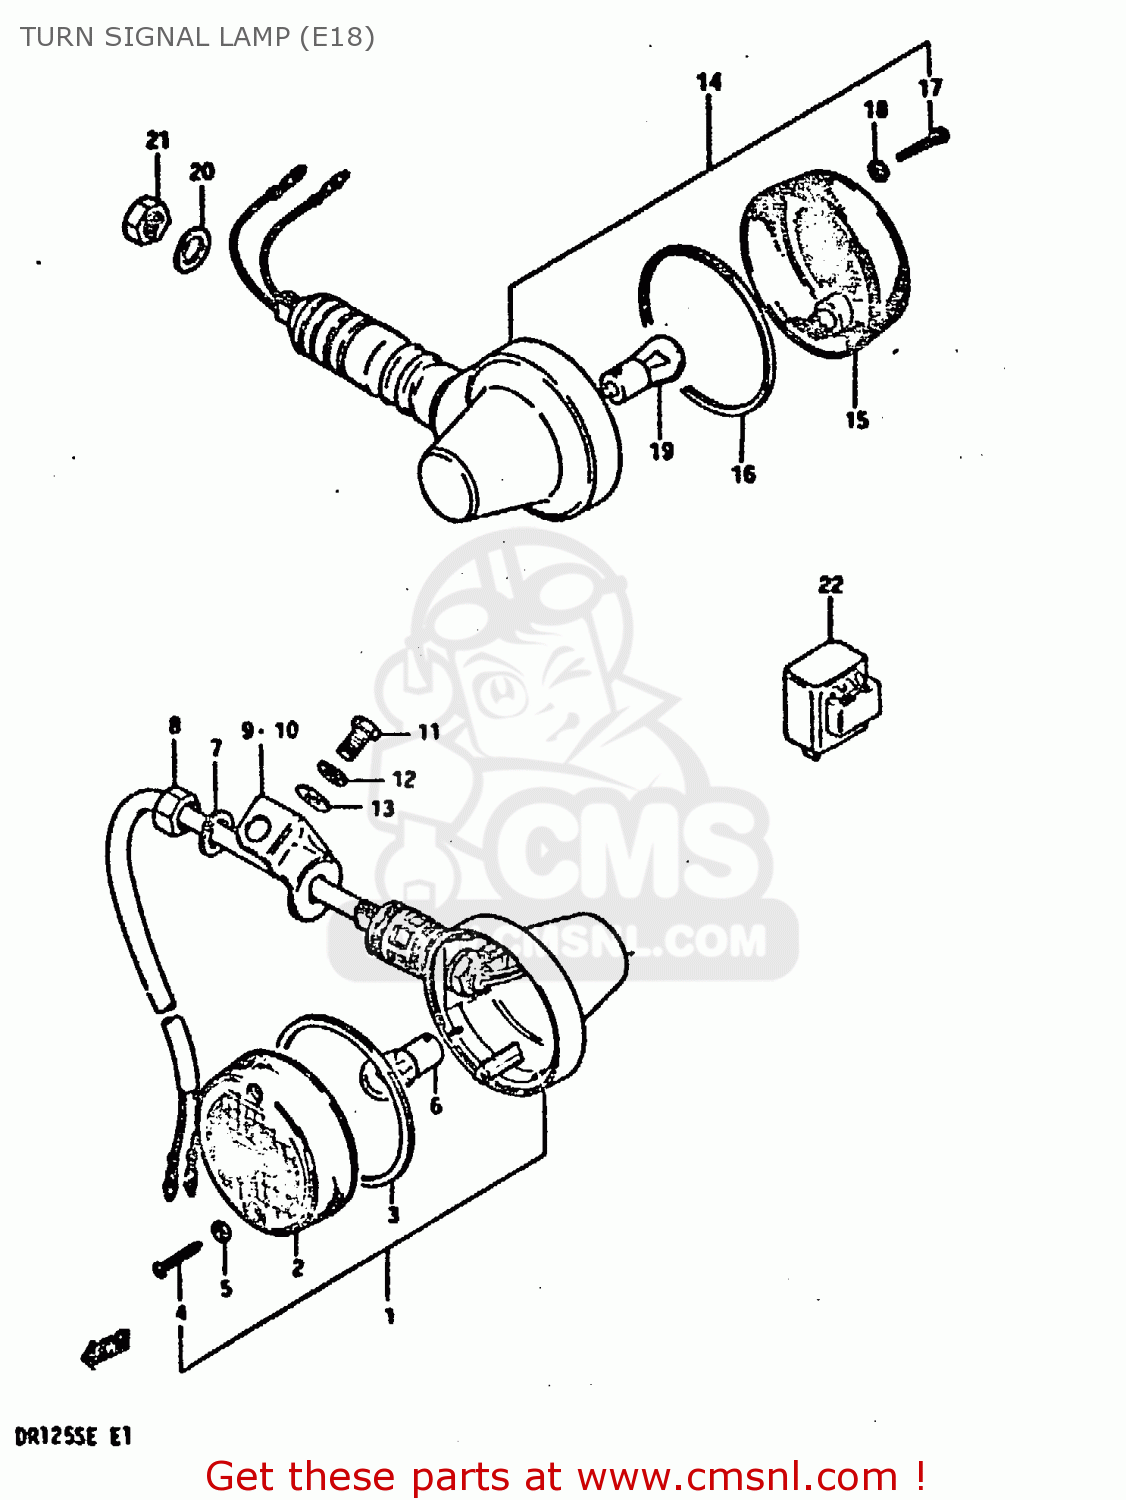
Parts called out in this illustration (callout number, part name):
1	LAMP, FRONT TURN SIGNAL
2	LENS
3	GASKET (NAS)
4	SCREW ,4X25
5	GASKET (NAS)
6	BULB(12V21W)
7	WASHER,LOCK 12
8	NUT
9	BRACKET,TURNSIGNAL LAMP,R
10	BRACKET,TURNSIGNAL LAMP,L
11	BOLT
12	LOCK WASHER
13	WASHER
14	LAMP, REAR TURN SIGNAL
15	LENS
16	GASKET (NAS)
17	SCREW TAPP.
18	GASKET (NAS)
19	BULB(12V21W)
20	WASHER,LOCK 12
21	NUT
22	RELAY ASSEMBLY,TURN SIGNAL
